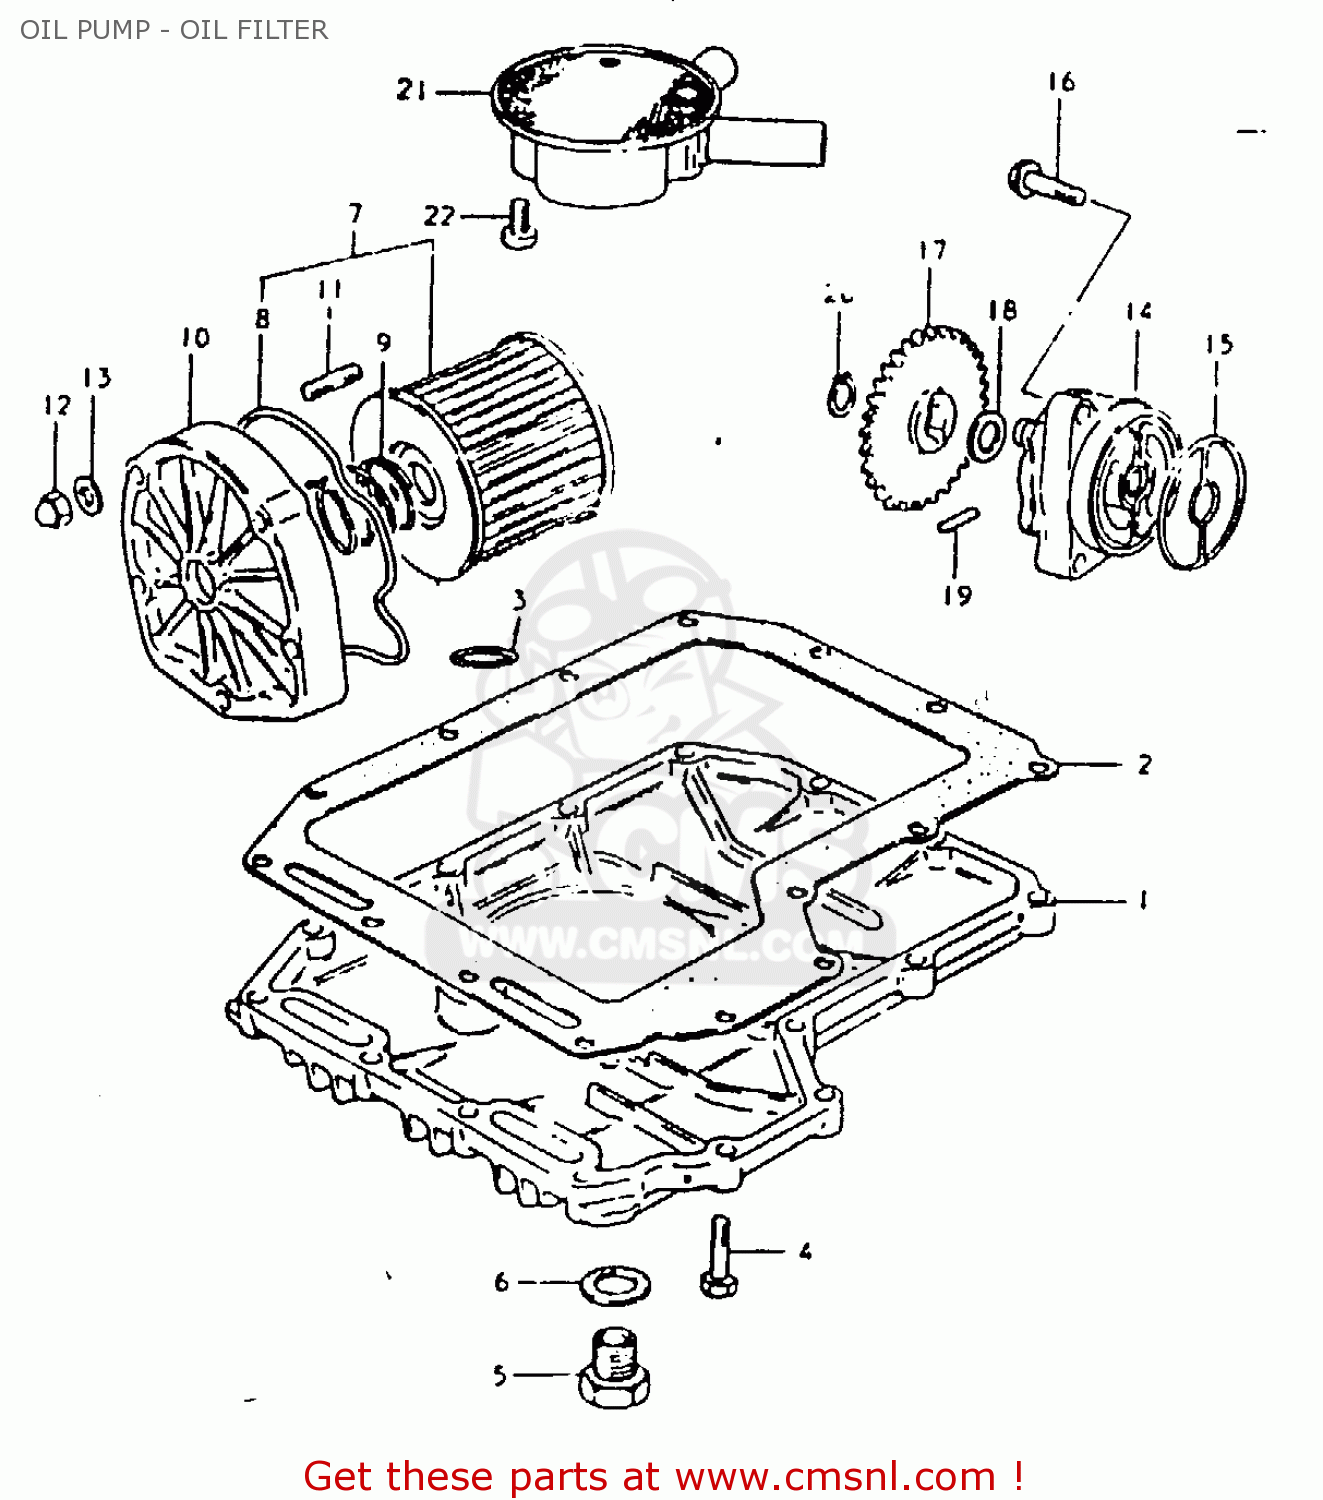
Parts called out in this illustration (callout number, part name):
1	PAN,OIL
2	GASKET,OIL PAN (MCA)
3	O RING(D:3.2,ID:12.9)
4	BOLT
5	PLUG
6	GASKET(14X19.2X2) (NAS)
7	ENGINE OIL FILTER SET
8	O RING,OIL FILTER CHAMBER CAP
9	SPRING
10	CAP,ENG OIL FLTR OUTER CHAMBER
11	STUD 6X25
12	NUT
13	WASHER
14	PUMP ASSY,ENGINE OIL
15	O-RING,OIL PUMP
16	BOLT(6X32)
17	GEAR,OIL PUMP DRIVEN
18	SHIM
19	PIN(4X15.8)
20	CIRCLIP
21	STRAINER,ENGINE OIL
22	SCREW 6X12
